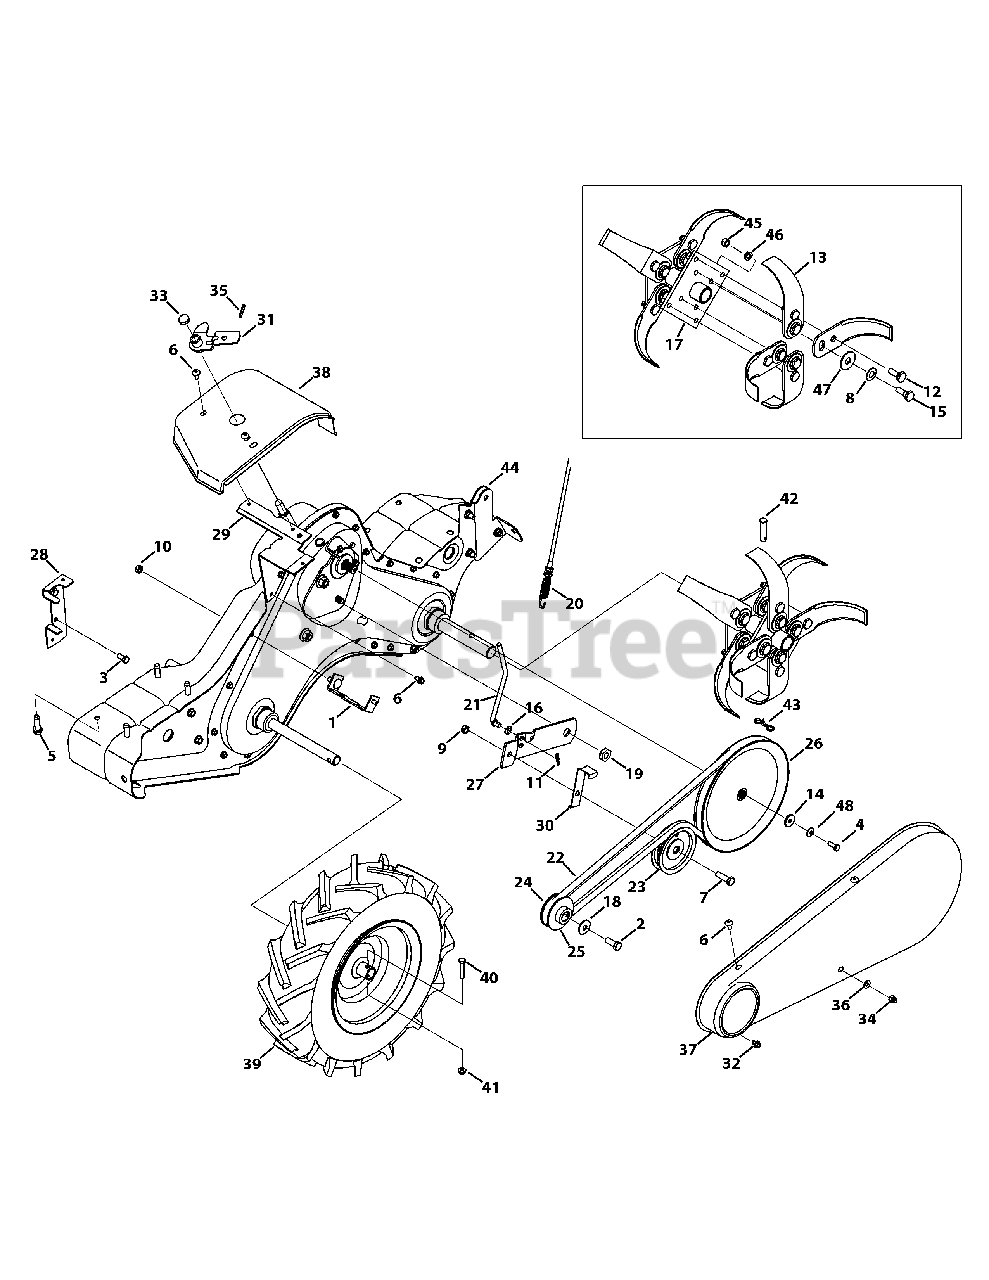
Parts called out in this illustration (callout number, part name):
1	Belt Cover Bracket Assembly
2	Hex Head Screw, 3/8-24 x 1.00
3	Hex Bolt, 5/16-24 x .625
4	Hex Bolt, 1/4-28 x .75"
5	Screw, 3/8-16 x 1.250
6	Hex Washer Screw
7	Hex Head Screw, 3/8-16 x 1.25
8	Washer, Bell, .525 x 1.00 x .050
9	Jamlock Nut, 3/8-16
10	Flangelock Nut, 5/16-18
11	Cotter Pin, .072 DIA. x 1.13 LG
12	Screw, Shoulder, 3/8-24 x 1/2 x .180
13	Articulating Tine
14	Washer, Flat, .265 x .938 x .120
15	Screw, Shoulder, 3/8-24 x 1/2 x .325
16	Washer, Spring, .317 x .625 x .020
17	Tine Adaptor Assembly
18	Washer, Bell, .396 x 1.140 x .095
19	Shoulder Nut, 7/16-20
20	Clutch Cable
21	Idler Pulley Rod
22	Belt, 4L x 58.16 LG
23	Flat Idler Pulley w/ Flanges, 3.75 O.D.
24	Engine Pulley, Inner Half
25	Engine Pulley, Outer Half
26	Input Pulley, 4L x 8.594
27	Idler Pulley Bracket
28	Belt Keeper Bracket, B&S 6.5 HP
29	Shift Cover Bracket
30	Idler Belt Keeper
31	Shift Crank Assembly
32	Screw, 1/4-20 x 0.375
34	Lock Nut, Cap, 1/4-28
35	Spiral Pin, 3/16 x 1.00
36	Washer, Flat, .271x .630 x .065
37	Belt Cover
38	Shift Cover
39	Wheel, 16 x 4.6 x 8
40	Hex Head Screw, 1/4-20 x 1.50
41	Flangelock Nut, 1/4-20
42	Clevis Pin, .375 x 1.75
43	Cotter Pin, Bow-Tie
44	Complete Gear Case Assembly
45	Hexlock Nut, 3/8-24
46	Washer, Lock, 3/8
47	Washer, Flat, .51 x 1.5 x 0.07
48	Bell Washer, .265 x .750 x .060
